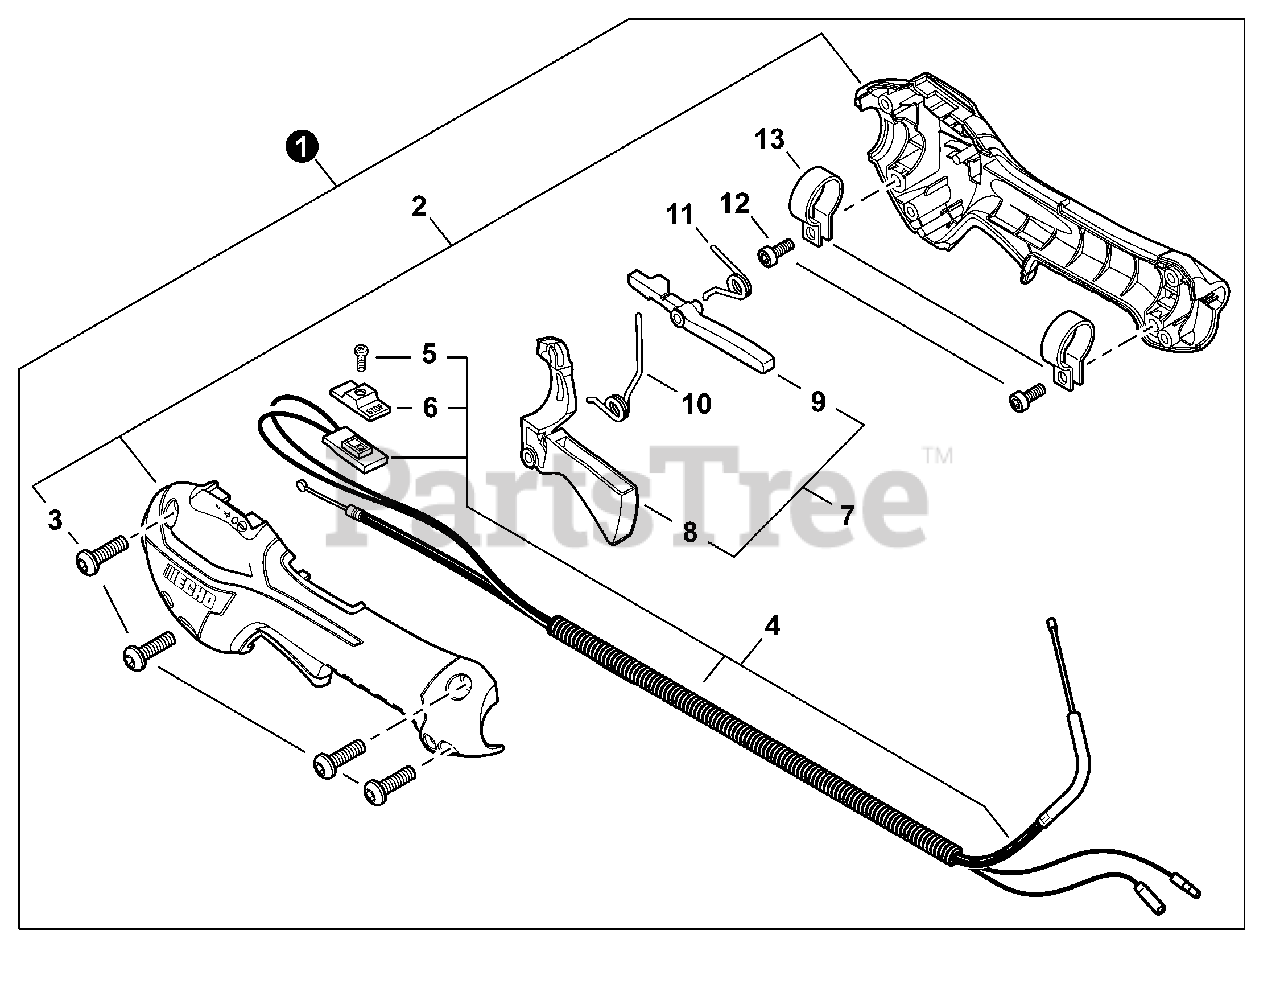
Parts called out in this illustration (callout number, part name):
1	CONTROL HANDLE ASSY
2	CONTROL HANDLE KIT
3	BOLT, TORX 5×16
4	CABLE ASSY, CONTROL
5	SCREW 3×10
6	KNOB, SWITCH - ORANGE
7	THROTTLE LOCKOUT KIT
8	TRIGGER, THROTTLE
9	LEVER, THROTTLE LOCKOUT
10	SPRING, TORSION
11	SPRING, TORSION
12	BOLT, TORX 5×16
